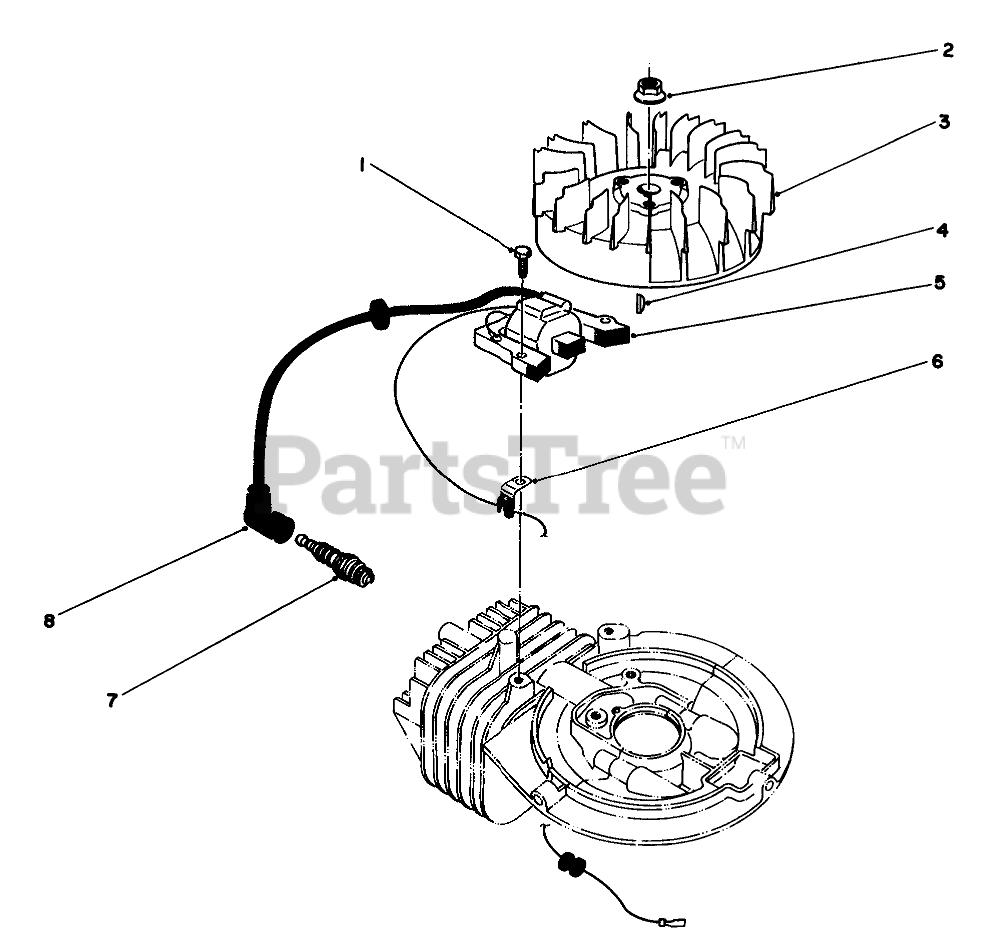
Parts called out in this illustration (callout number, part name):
1	SCREW
3	FLYWHEEL
5	COIL-MAGNETO
6	CLAMP
7	Sparkplug
8	CAP-SPARKPLUG
